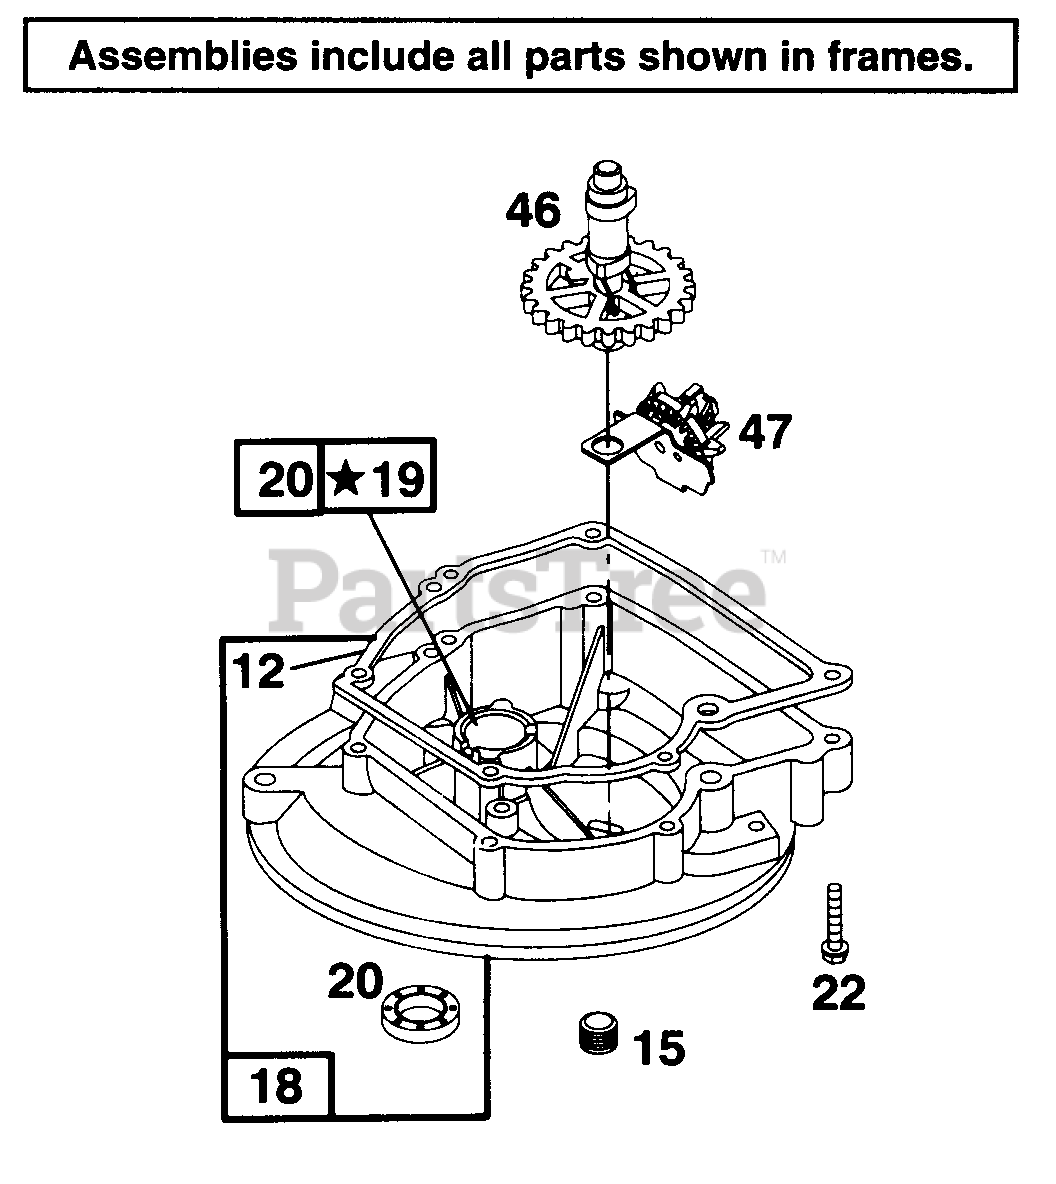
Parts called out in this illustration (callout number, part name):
12	Gasket--Crankcase (.015" Thick, Standard)
15	Plug--Oil Drain
18	Sump--Engine
19	Bushing--Engine Sump (Plain)
20	Seal--Oil
22	Screw--Mtg. Sem
47	Oil Slinger Gear and Bracket
